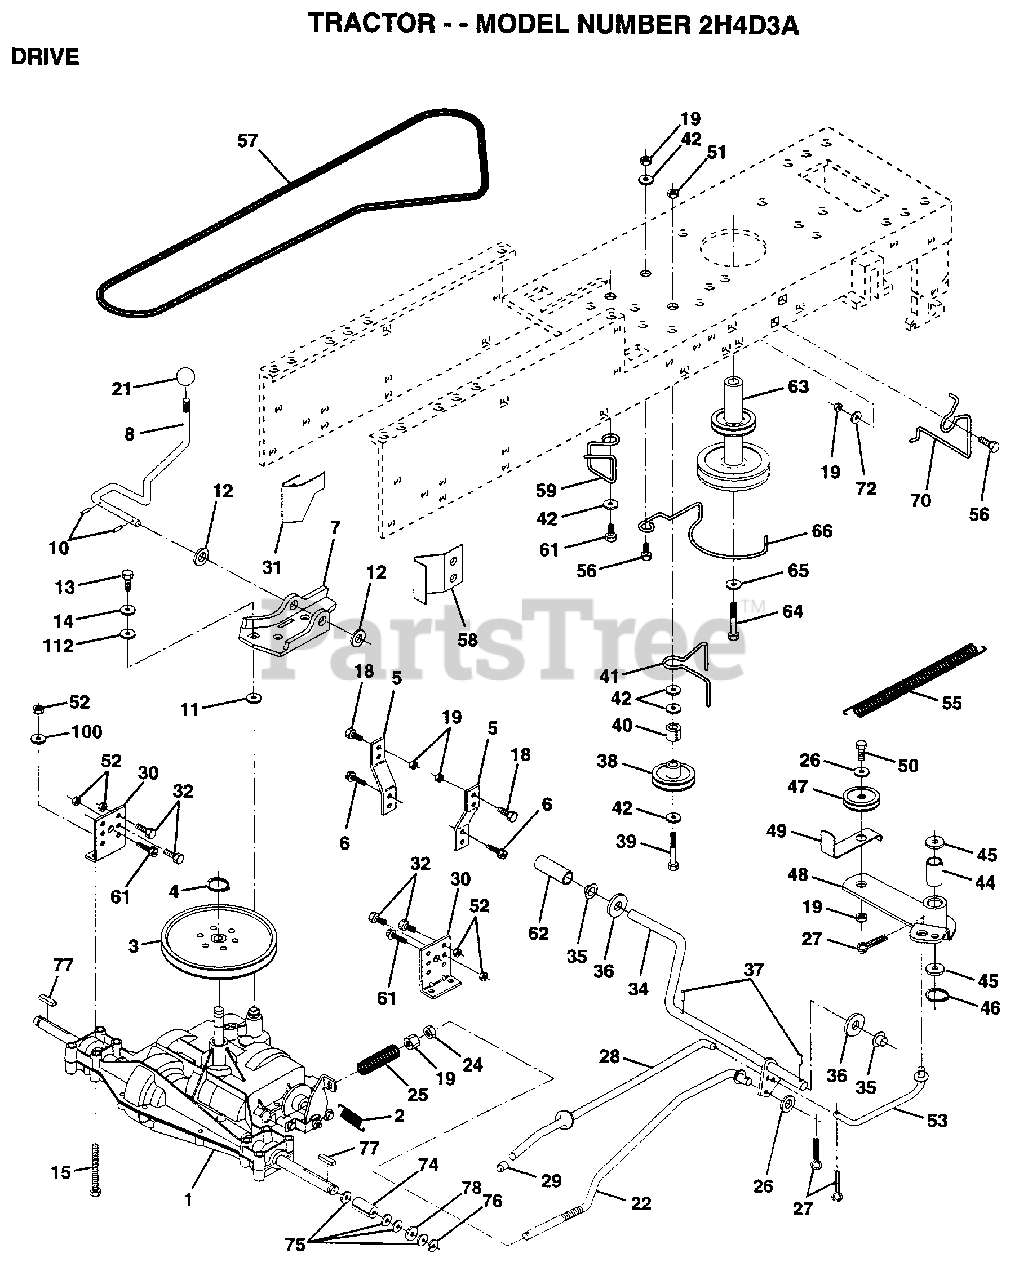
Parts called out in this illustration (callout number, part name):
2	SPRING.BRAKE.RETU
3	PULLEY TRANS
5	STRAP TORQUE
6	SCREW
8	SHIFT ROD
10	PIN COTTER 1/8
11	WASH-SHFT PLT LT
12	WASHER
13	BOLT.1/4-28.W/PAT
14	LOCKWASHER
15	BOLT HEX
18	BOLT
19	NUT
21	KNOB T (1/2-HOLE)
22	BRAKE ROD
24	NUT
25	SPRING ROD LT
26	WASHER
27	COTTER PIN
28	ROD.BRAKE.PARK.LT
29	PLUNGER CAP T
30	TRANSAXLE MTG BKT
31	"KEEPER,BELT LH T"
32	BOLT
34	SHAFT.PEDAL.FOOT
35	NYLON BEARING
36	WASHER LT
38	PULLEY.IDLER.FLAT
39	BOLT
40	SPACER T
41	BELT KEEPER LT
42	WASHER
44	"LY, BEARING"
45	WASHER LT
46	KLIP RING
48	ARM IDLER
49	RETAIN BELT
53	"LINK, CLUTCH T"
55	"SPRING, RETURN LT"
58	"KEEPER,BELT RH T"
59	KEEPER BELT CNTSP
61	SCREW
62	PULLEY.ENGINE
64	BOLT
65	LOCKWASHER
66	KEEPER.BELT.ENG.L
70	KEEPER BELT ENG
72	WASHER
74	SPACER LT
75	WASHER
76	E-RING LT
77	SQUARE KEY
78	WASHER
100	WASHER M
112	WASHER LT
